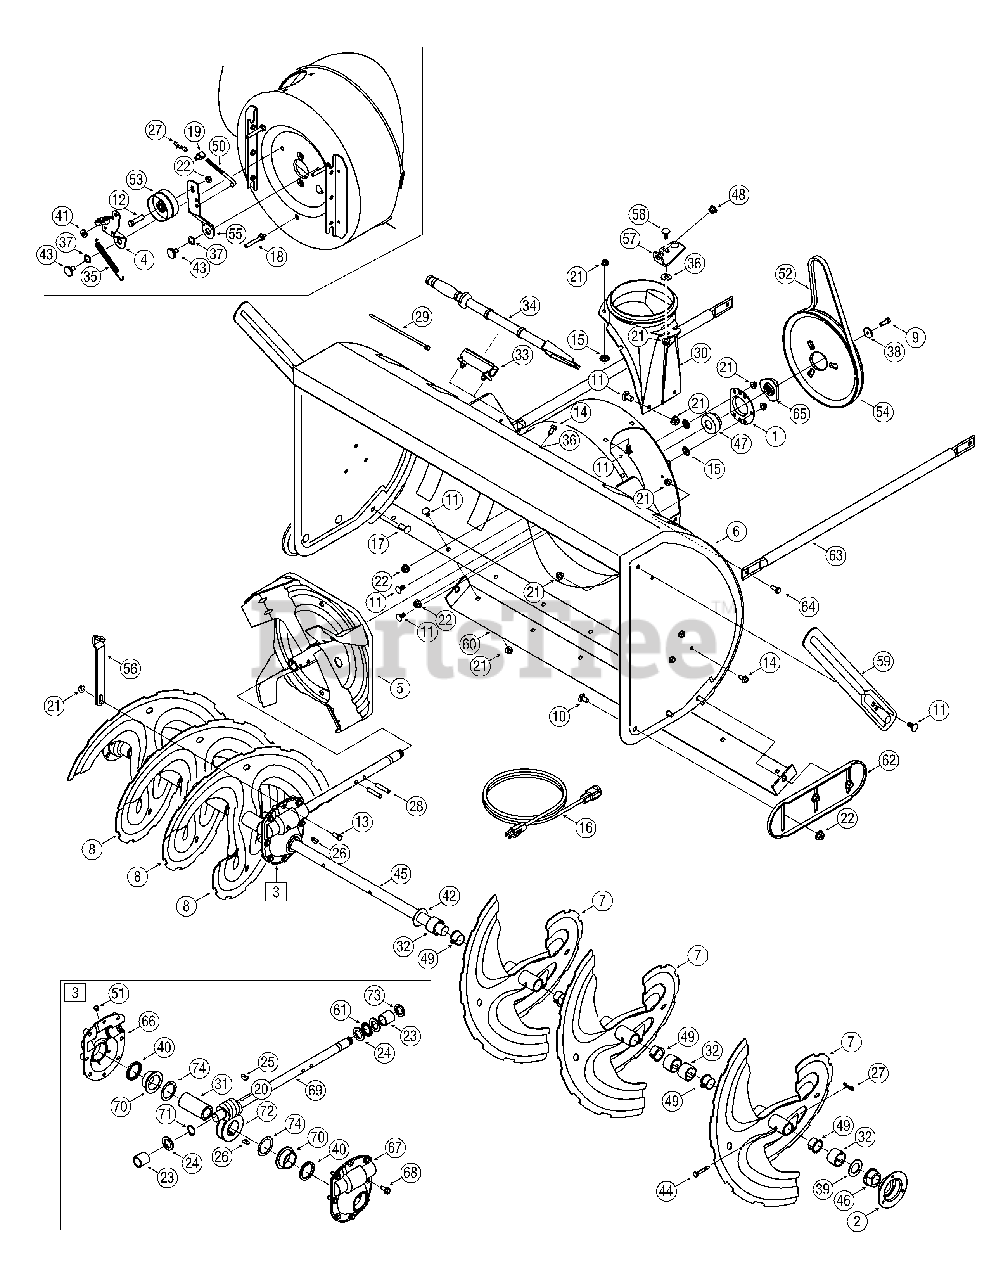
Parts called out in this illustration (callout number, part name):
1	Housing, Bearing
3	Gear Box Assembly, Auger
4	Bracket Assy, Auger Brake
5	Impellar, 16"
6	Housing, Auger - 45"
7	Spiral Assy, LH
8	Spiral Assy, RH
9	Screw, 5/16-24 x .875
10	Bolt, Carriage, 3/8-16 x .750
11	Screw, Carriage, 5/16-18 x .75
12	Scr, Hex Cap, 3/8-24 x 1.5
13	Scr,Hex Cap, 5/16-18 x 1.00
14	Screw, 5/16-18 x .750
15	Nut, Push
16	Extension Cord, 110V
17	Bolt, Carriage, 3/8-16 x 1.0
18	Screw, 5/16-18 x .4300
19	Ferrule
20	Gear, Worm Dbl Thread
21	Nut, Flnge Lk, 5/16-18
22	Nut, Flg Lk, 3/8-16
23	Sleeve
24	Washer, Flat .88 ID x .38 OD
25	Key, Hi Pro, 3/16 x 3/4
26	Key, Woodruff,1/4 x 3/4
27	Pin, Bowtie Cotter
28	Pin, Spirol, 5/16 x 1.75
29	Tie, Cable
30	Adapter, Chute, 6"
31	Shf, Gear, Worm
32	Spacer, 1.0 x 1.5 x 1
33	Clip, Mounting
34	Tool, Cleanout
35	Spring, Extension
36	Washer, .349 x .879 x .063
37	Washer, .625 x .885 x .015
38	Washer, Flat, .34 x 1.50 x .150
39	Spacer, 1.004 x 1.375 x .25
40	Oil Seal
41	Washer, .344 x .75 x .12
42	Washer, 1.01 x 1.86 x .06
43	Screw, Shoulder, .625 x .17
44	Pin, Shear, .25 x 1.75
45	Axle, Spiral, 45"
46	Bearing, Flange w/Flats
47	Bearing, Self Aligning
48	Bushing, Nylon
49	Bushing, Flange, 1.051 x 1.16
50	Rod, Auger Idler
52	V Belt,1/2 x 42
53	Pulley, Flat Idler, 2.75 OD
54	Pulley, Auger Drive, 10.0
55	Bracket, Auger Idler
56	Bracket, Gear Box Support
57	Bracket, Chute Crank
58	Screw, Carriage, 5/16-18 x 1.00
60	Plate, Shave, 45"
61	Brg, Thrust
62	Shoe, Skid
63	Support Tube
64	Screw, 5/16-18 x .75
65	Pulley, Adapter, .75 Dia.
66	Hsg Assy Auger RH (Inc. 40 & 70)
67	Hsg Assy Auger LH (Inc. 40 & 70)
68	Screw, LD, 5/16-18 x .750
69	Shf, Drive, Auger
70	Flange Bearing
71	Ext, Ret, Ring
72	Gear, Worm, LH
73	Seal, Oil
74	Washer, Flat, 1.52 ID x 2.0 OD
